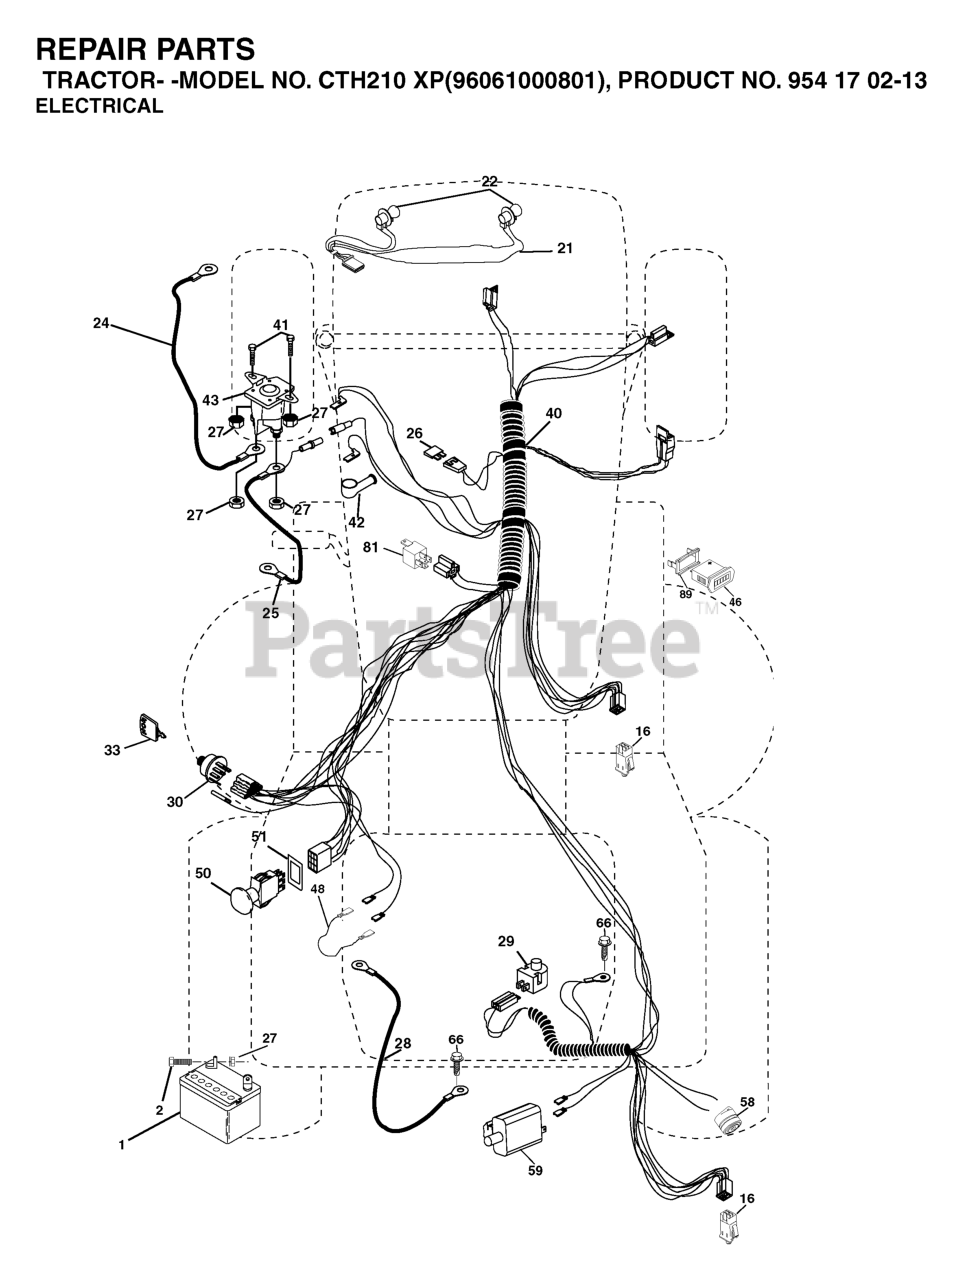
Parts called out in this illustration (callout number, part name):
1	BATTERY 12V .35 AMP
2	BOLT.HEX.1/4.X.3/4.DICHROMATE
16	SWITCH INTERLOOK PUSH-IN
21	HARNESS.W/LIGHT SOCKET
24	BATTERY CABLE
25	CABLE BATTERY
26	FUSE 20AMP
27	NUT
28	CABLE GROUND
29	RP.SWITCH.PLUNGER.NC.GRAY
30	IGNITION SWITCH
33	KEY MLD GEN DELTA
41	BOLT
42	TERMINAL COVER
43	SOLENOID
46	HOUR METER
48	ADAPTER.AMMETER
50	RP.PTO.SWITCH.8 TERMINAL.BLACK
51	FRAME RETAINING RING
58	BUZZER
59	.WITCH.FULL BAGGER.INDICATOR
81	RELAY.ASSY.T
89	BRACKET SNAP-IN HOURMETER
